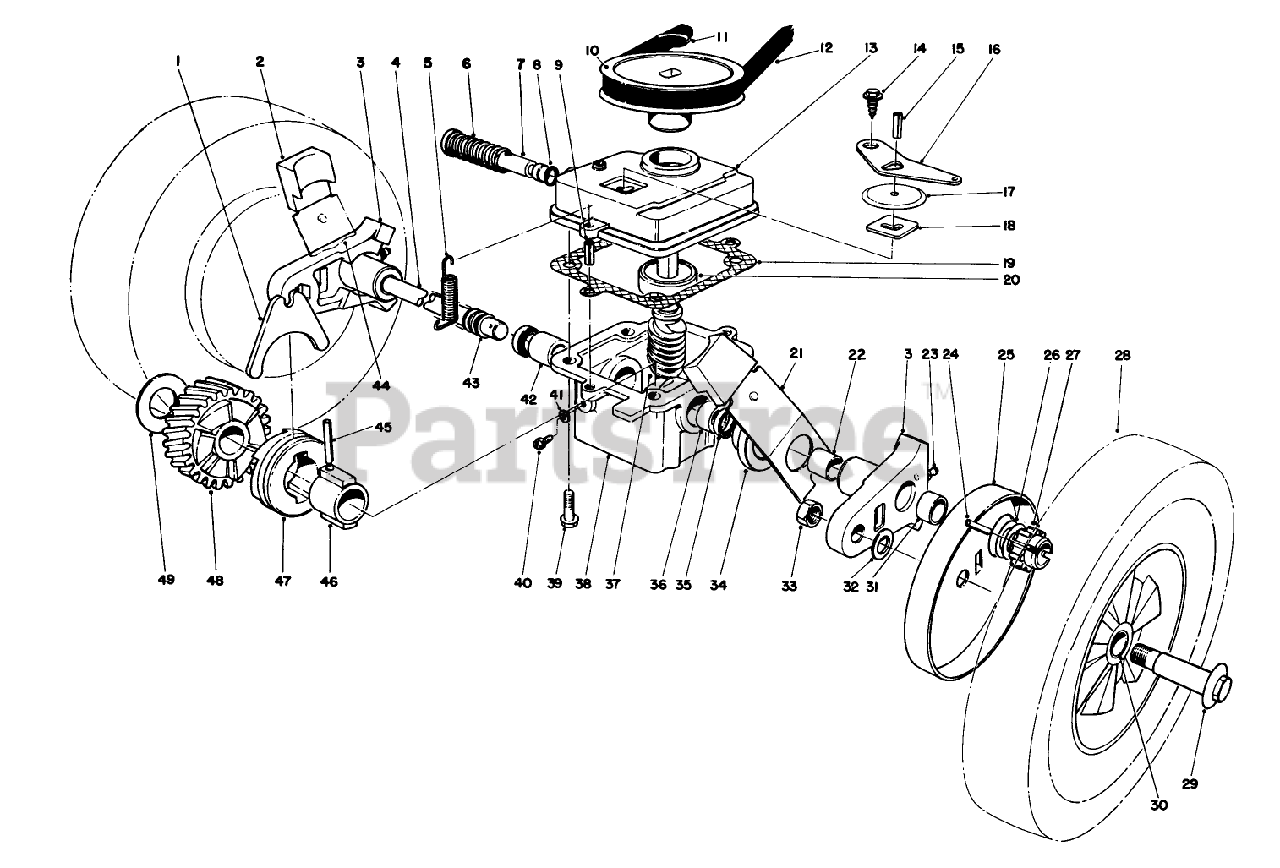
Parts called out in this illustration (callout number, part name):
1	SHIFTER FORK
2	KNOB-ARM
3	PIVOT ARM ASM
4	DRIVE SHAFT (SERVCE)
5	TENSION SPRING
6	SPRING
7	SHIFTER ROD
8	O-RING
9	3/16 X 1/2 ROLL PIN
10	PULLEY
11	PUSH-ON 93-3236
12	BELT-V
15	PIN-ROLL
16	SHIFTER ARM
17	TRANS DUST COVER
18	LATCH PLATE
19	GASKET
20	BEARING - BALL
22	BUSHING
23	FITTING-GREASE
25	WHEEL COVER
27	PINION GEAR 14T
28	WHL/GEAR/TIRE PKG
29	WHEEL BOLT
30	BUSHING
31	BUSHING
32	WASHER
33	NUT-LOCK
34	CAP-END
35	SEAL-OIL
36	BUSHING
37	WORM SHAFT & GEAR SET
38	GEAR CASE ASM
40	NYLON SCREW
41	FILL PLUG GASKET
42	BUSHING
43	COVER-SHAFT, DRIVE
44	SPRING ARM ASM SP RH
45	COIL PIN
46	SLEEVE
47	CLUTCH JAW
48	Helical Gear
49	THRUST WASHER
